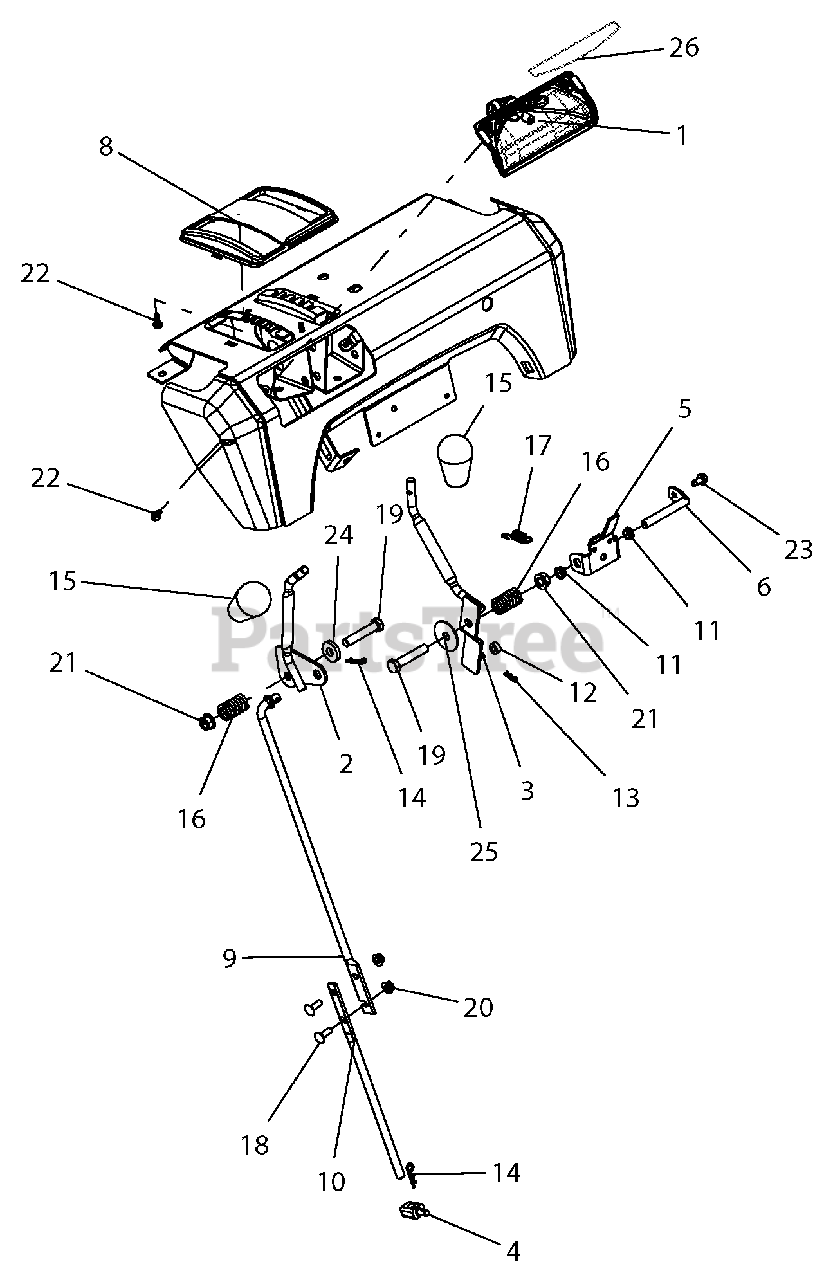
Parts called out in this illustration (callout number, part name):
1	HEADLIGHT ASSY, HALOGEN 20W
2	WELDMENT, CONTROL LEVER(SHIFT)
3	WELDMENT, CONTROL LEVER (DEFL)
4	PIVOT,SHIFT ROD .375-16(TRUNN)
5	BRACKET, INTERLOCK ARM
6	ROD, PIVOT - INTERLOCK
8	BEZEL, SHIFT
9	ROD, SHIFT - UPPER
10	ROD, SHIFT - LOWER
11	BUSHING, POLYLINER-.38 SNAPIN
12	BSHG-SLV .265X.500X.219
13	PIN-HAIR INT .06X.18X.77
14	PIN-HAIR INT .08X.18X1.18 YWZC
15	KNOB,SOFT TEARDROP,PUSH-ON GRY
16	SG-COMP .125X.781X1.250
17	SPRING-EXT .047X.438X1.45
18	@BLT-RDHDSQNK .25-20X.75 G5YZ
19	@BLT-HEX .38-16X2.00 GR5 YWZC
20	@NUT-LK-CTR-FLG .25-20 YWZC
21	@NUT-LK-TOP-FLG .38-16 YWZC
22	SCR-TAP #10X.50 BOSS INDHXHD
23	SCR-TAP .25-20X.50 HWH TR YWZ
24	WSHR-FL-STL .406X1.00X.188 YWZ
25	WSHR-FL-STL .380X1.50X.062 YWZ
26	DECAL, HEADLIGHT, DOT MATRIX
